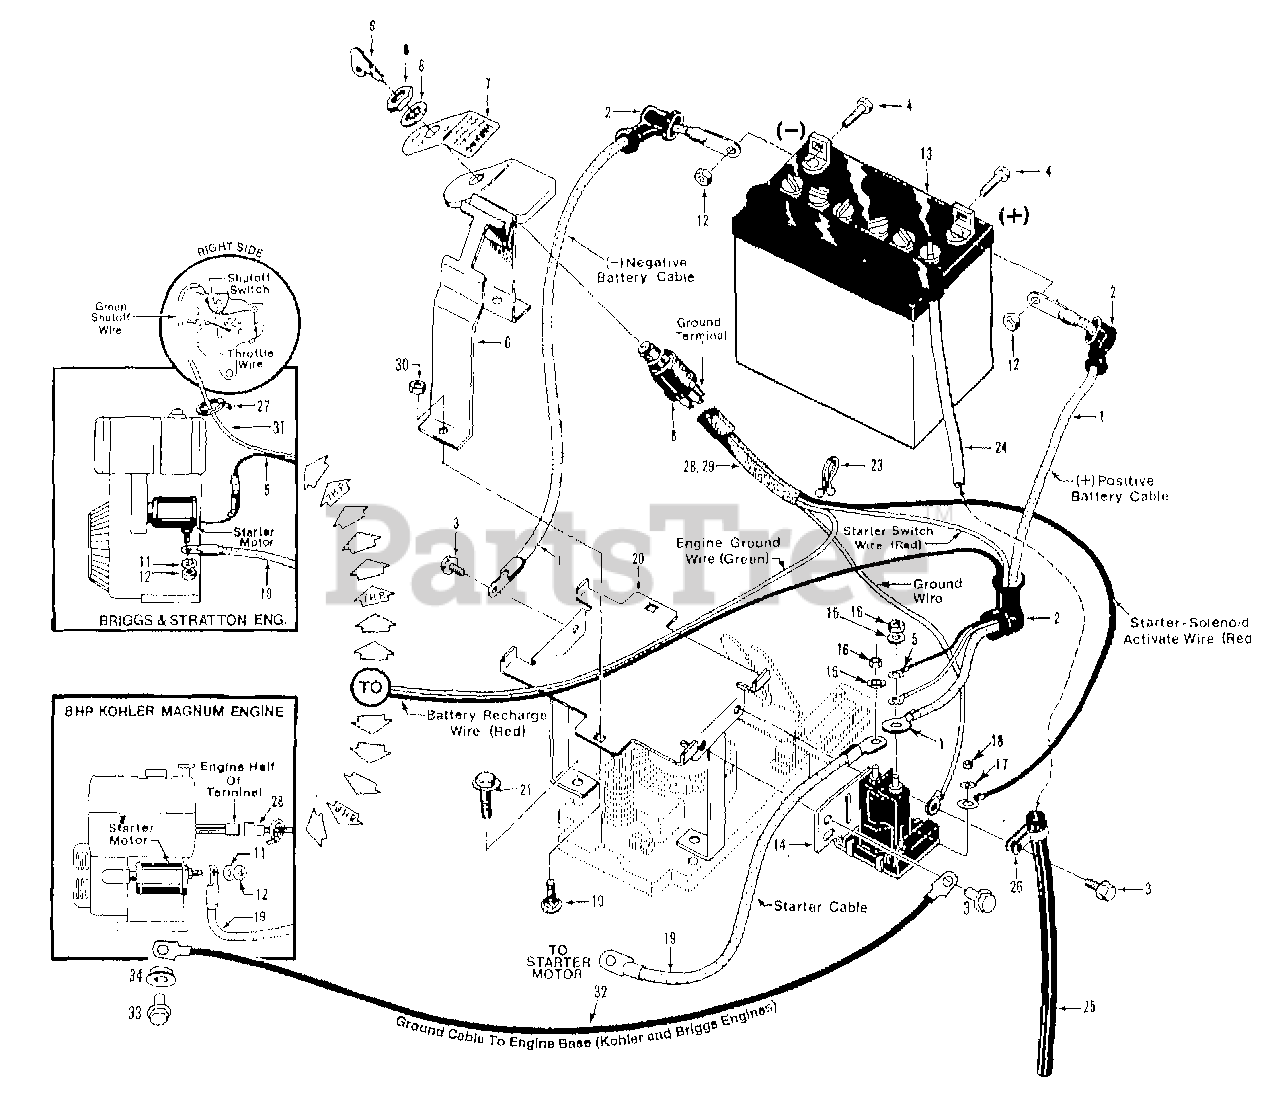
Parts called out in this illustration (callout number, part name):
1	CABLE-BATTERY 10"
2	BOOT-BATTERY CABLE
3	SCR-HWH 1/4-20 X .5 STH
4	SCR-HH 1/4-20X.625
5	WIRE-RECHARGE 5&7 BRIGGS
6	KEYSWITCH W/DECAL HORSE
7	DECAL-IGNITION TILLERS
8	ASSM-KEYSWITCH ELEC TLR
9	KEYS-IGN T/BLAZER 1 PAIR
10	SCR-CARR 1/4-20X1.25
11	WASHER-LK .25 ZP
12	NUT-HEX 1/4-20 ZP
13	BATTERY-12 VOLT HORSE
14	SOLENOID
15	WASHER-LK .312 ZP
16	NUT-HEX 5/16-24
17	WASHER-EXTERNAL TOOTH 1
18	NUT-HH M10-32X.125
19	CABLE-BATTERY 12"
20	BRKT-BATTERY OPC PNT
21	SCR-HFLK 3/8-16X1.50
22	THIS REF. NO. NOT USED
23	TIE-TWIST LOCK
24	TUBE-VENT BATTERY/HSE
25	TUBING-RUBBER
26	CLAMP
27	TIE-RED
28	KIT-WIRE HARNESS ASSM
29	ASSM-WIRE HARNESS
30	NUT-HF/LK 1/4-20 ZP
31	ASSM-WIRE SWITCH/GROUND
31	CABLE-BATTERY 15"
32	CABLE-BATTERY 15"
33	SCR-HFLK 5/16-18X1.00 ZP
34	NUT-HFLK 5/16-18 ZP
